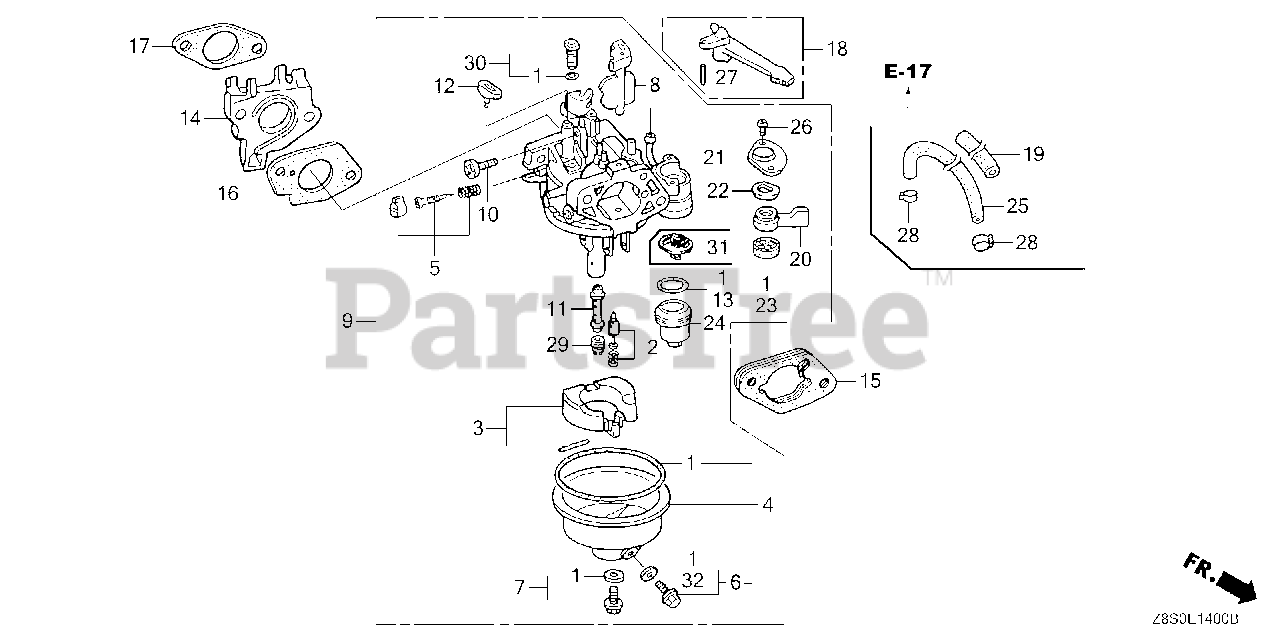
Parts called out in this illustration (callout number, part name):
1	GASKET SET (INCLUDE 16173-001-004) (INCLUDES 16173-001-004)
2	VALVE SET, FLOAT
3	FLOAT SET
3	FLOAT SET (CARBURETOR NO.)
4	CHAMBER SET, FLOAT
5	SCREW SET
5	SCREW SET (Honda Code 4219879). (CARBURETOR NO.)
6	SCREW SET, DRAIN
7	SCREW SET (CARBURETOR NO.)
8	CHOKE SET
9	CARBURETOR ASSY. (BE70U A)
9	CARBURETOR ASSY. (BE70R A)
10	SCREW, THROTTLE STOP
11	NOZZLE, MAIN (CARBURETOR NO.)
11	NOZZLE, MAIN
12	COLLAR, SET
13	GASKET, FUEL STRAINER CUP
14	INSULATOR, CARBURETOR
15	SPACER, CARBURETOR
16	GASKET, CARBURETOR
17	GASKET, INSULATOR
18	LEVER, CHOKE (STD)
20	LEVER, VALVE
21	PLATE, LEVER SETTING (CARBURETOR NO.)
22	SPRING, PETCOCK LEVER (CARBURETOR NO.)
23	GASKET, VALVE
24	CUP, FUEL STRAINER
26	SCREW, PAN (3X6)
27	PIN, SPRING (2X12)
29	JET, MAIN (#80)
29	JET, MAIN (#82)
29	JET, MAIN (#85) Use up to Engine SN BE81B B.
29	JET, MAIN (#88) Use up to Engine SN BE81B B.
30	JET SET, PILOT (#38)
30	JET SET, PILOT (#35)
31	FILTER, CUP (CARBURETOR NO.)
32	WASHER, PLAIN (6.2X10.7 DRAIN) (CARBURETOR NO.)
